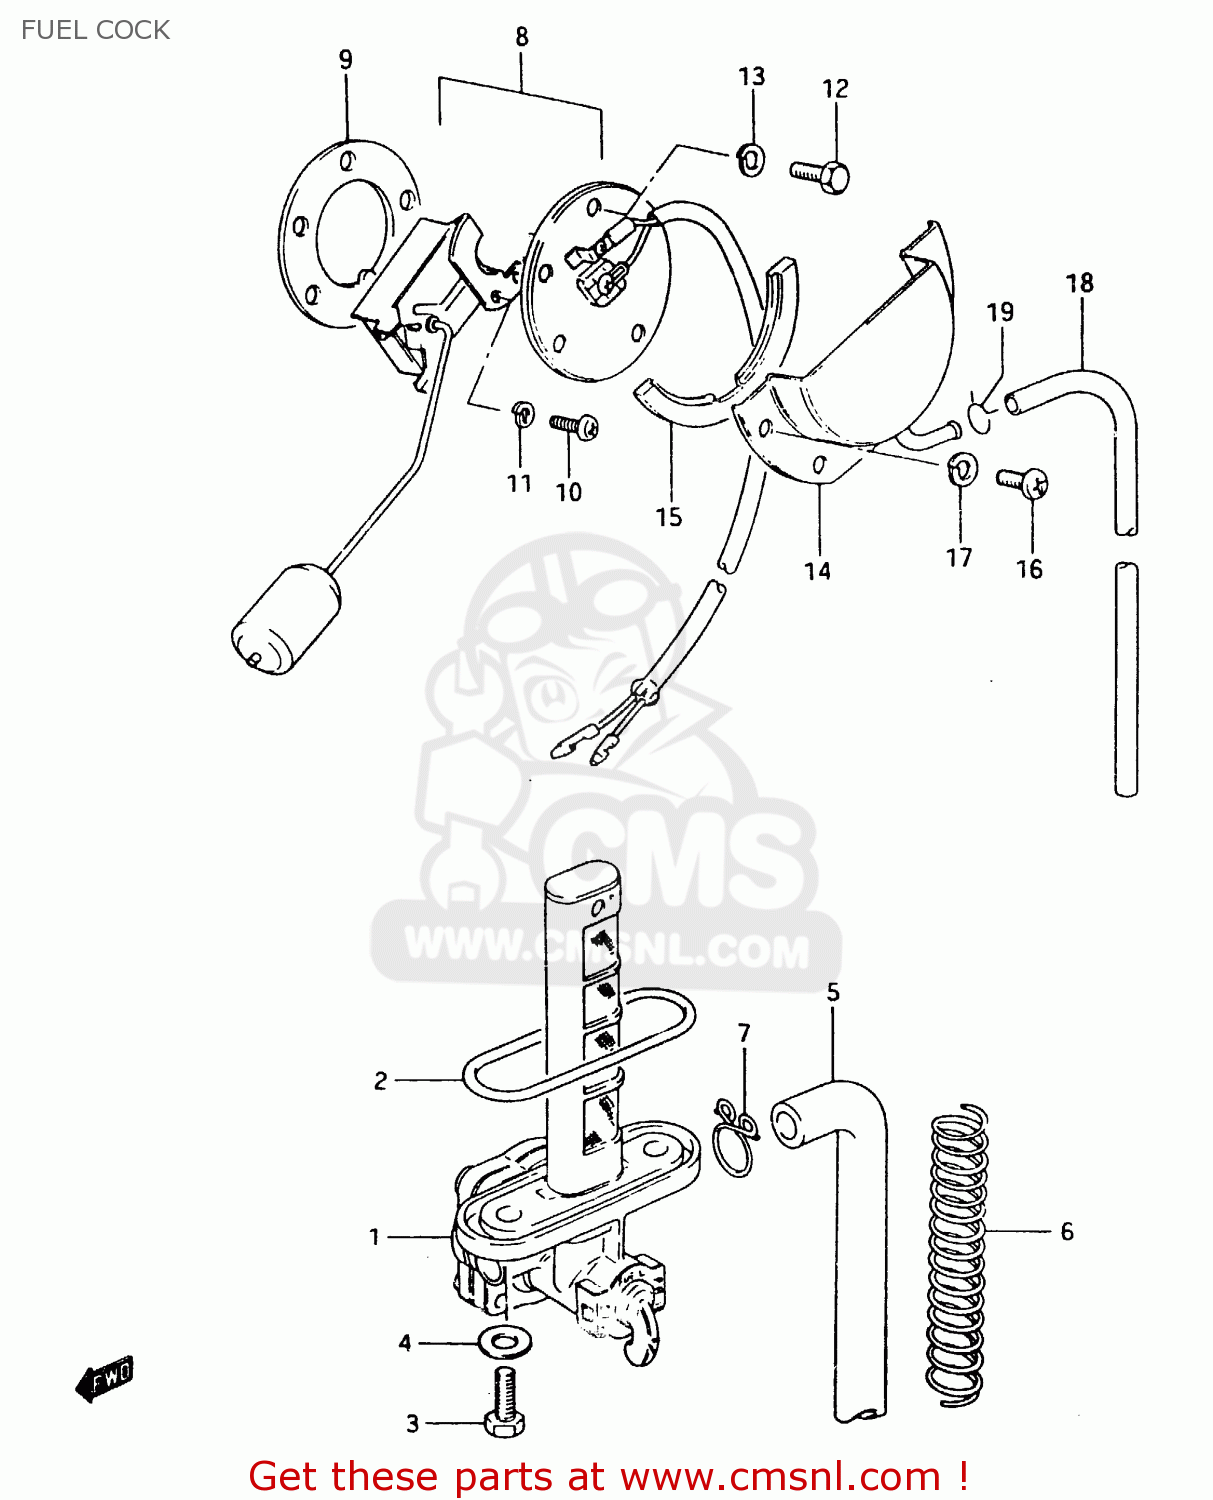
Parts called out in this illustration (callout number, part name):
1	COCK ASSEMBLY,FUEL
2	O RING
3	BOLT(6X20)
4	GASKET
5	HOSE
6	SPRING
7	CLIP
8	GAUGE ASSEMBLY,FUEL LEVEL
9	GASKET,FUEL LEVEL GAUGE (NAS)
10	SCREW 5X10
11	LOCK WASHER
12	BOLT 5X10
13	LOCK WASHER
14	PLATE,FUEL DRAIN
15	GASKET (NAS)
16	SCREW
17	LOCK WASHER
18	HOSE,FUEL
19	CLIP
